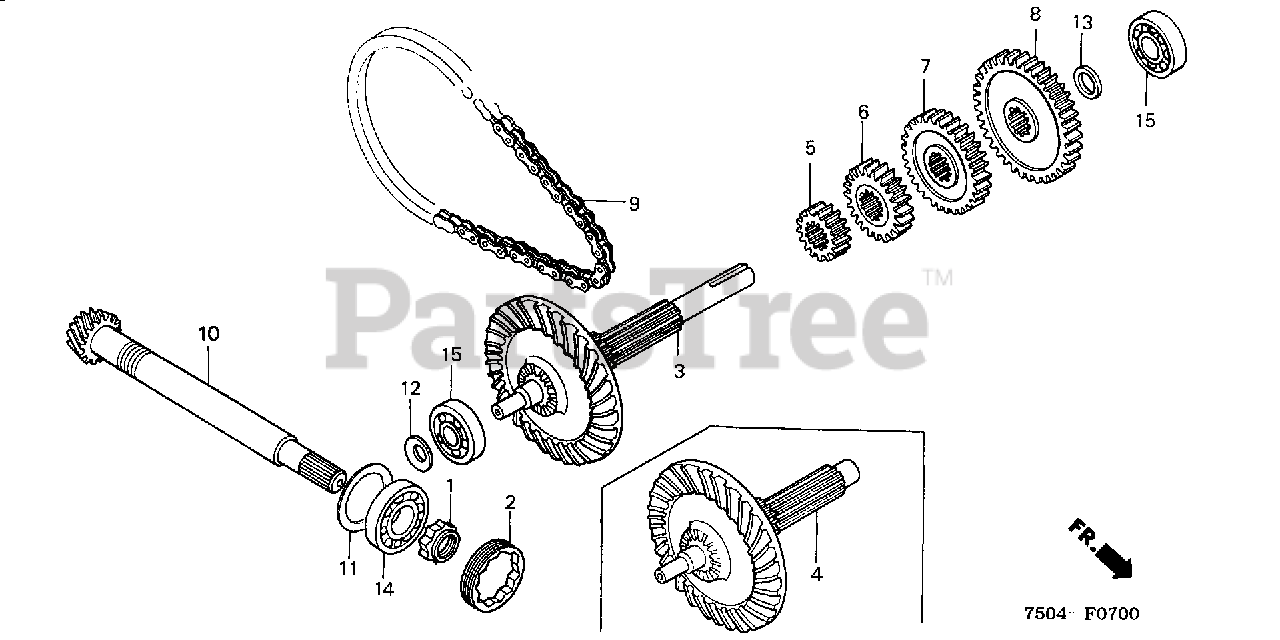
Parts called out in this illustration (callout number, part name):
1	NUT, LOCK (22MM)
2	NUT, LOCK (52MM)
4	SHAFT ASSY., MAIN
5	GEAR, MAIN SECOND (16T)
6	GEAR, MAIN THIRD (21T)
7	GEAR, MAIN FOURTH (28T)
8	GEAR, MAIN FIFTH (37T)
9	CHAIN, REVERSE
10	SHAFT, INPUT
11	SHIM A, PINION GEAR
11	SHIM B, PINION GEAR
11	SHIM C, PINION GEAR
11	SHIM D, PINION GEAR
11	SHIM E, PINION GEAR
11	SHIM F, PINION GEAR
11	SHIM G, PINION GEAR
12	WASHER, CURVED (NOT AVAILABLE)
13	WASHER A, SETTING SHAFT
13	WASHER B, MAINSHAFT
13	WASHER, CM SHAFT
13	WASHER D, MAINSHAFT
13	WASHER E, MAINSHAFT
13	WASHER F, MAINSHAFT
13	WASHER G, MAINSHAFT
13	WASHER H, MAINSHAFT
13	WASHER I, MAINSHAFT
13	WASHER J, MAINSHAFT
14	BEARING, RADIAL BALL (62/22)
15	BEARING, RADIAL BALL (6203)
